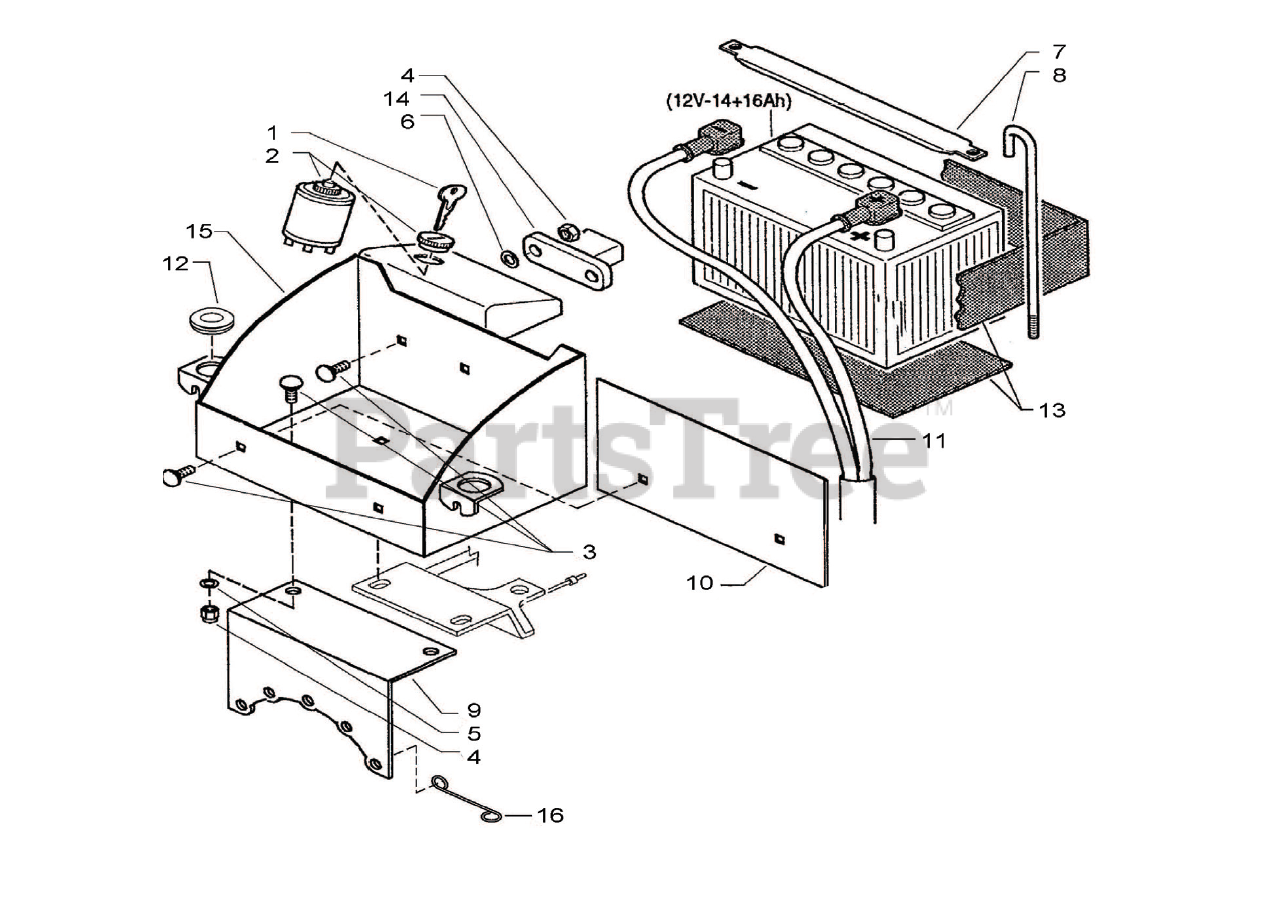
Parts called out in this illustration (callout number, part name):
2	SWITCH
3	SCREW
4	LOCKNUT, M6
5	WASHER FLAT M6.4X12
6	WASHER, FLAT M9X24
7	BRACKET, BATTERY 8
9	BATTERY SUPPORT
10	SHIELD 6.5 & 8HP INTEK
11	BATTERY CABLES
12	SUPPORT, BODY GAURD
13	PAD SET
14	SOLENOID
15	BATTERY BOX
16	SUPPORT, THROTTLE CABLE
